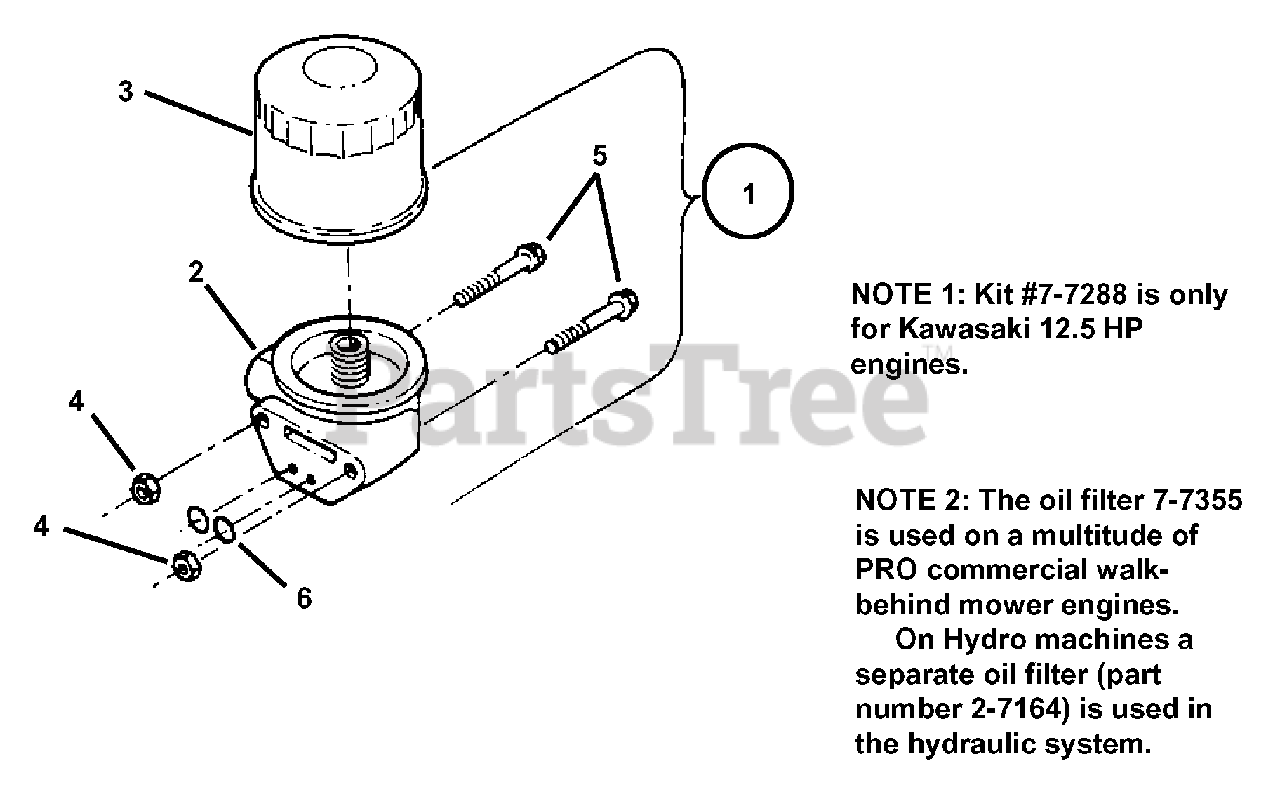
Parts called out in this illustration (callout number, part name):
1	KIT, Oil Filter
2	BASE, Oil Filter
3	FILTER, Oil
4	NUT, M8-1.25, Hex Nyloc
5	BOLT, M8 x 1.25 x 45 Hex
6	SEAL, Oil
27164	FILTER, OIL
